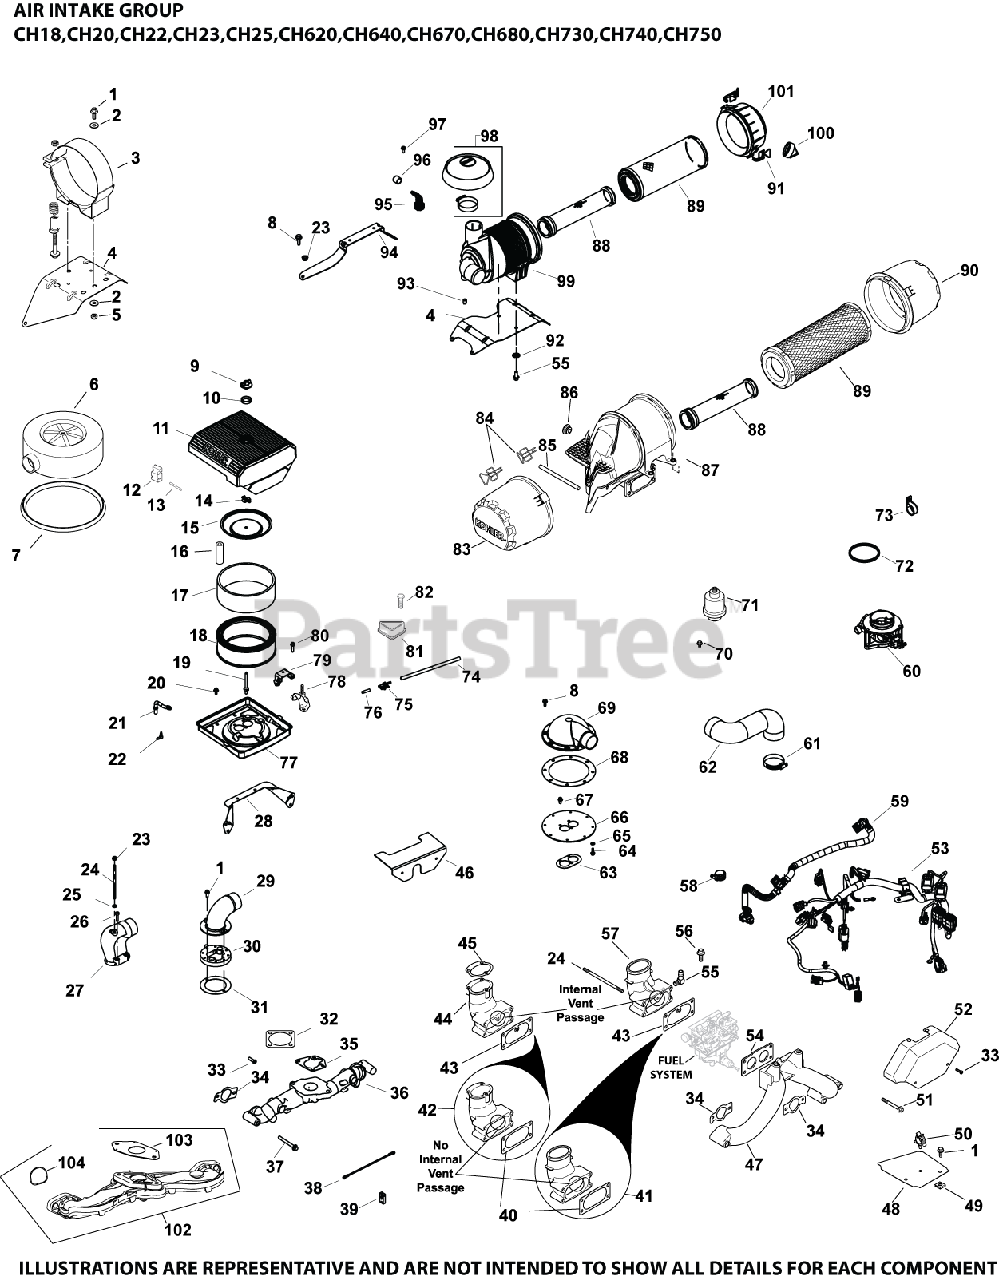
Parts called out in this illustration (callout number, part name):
1	SCREW, FLG M6X1.0X16
29	ADAPTER, REMOTE AIR CLEANER
30	ADAPTER ASSY (CH18 / 20)-USE 24 029 97-S
31	GASKET, ADAPTER
33	SCREW, PHL HD 11-16X3/4"
34	GASKET, INTAKE MANIFOLD USE 24 041 79-S
35	GASKET, AIR CLEANER BASE
36	MANIFOLD, METAL INTAKE
37	SCREW, FLG M6X1.0X55
46	SHIELD, DEBRIS
